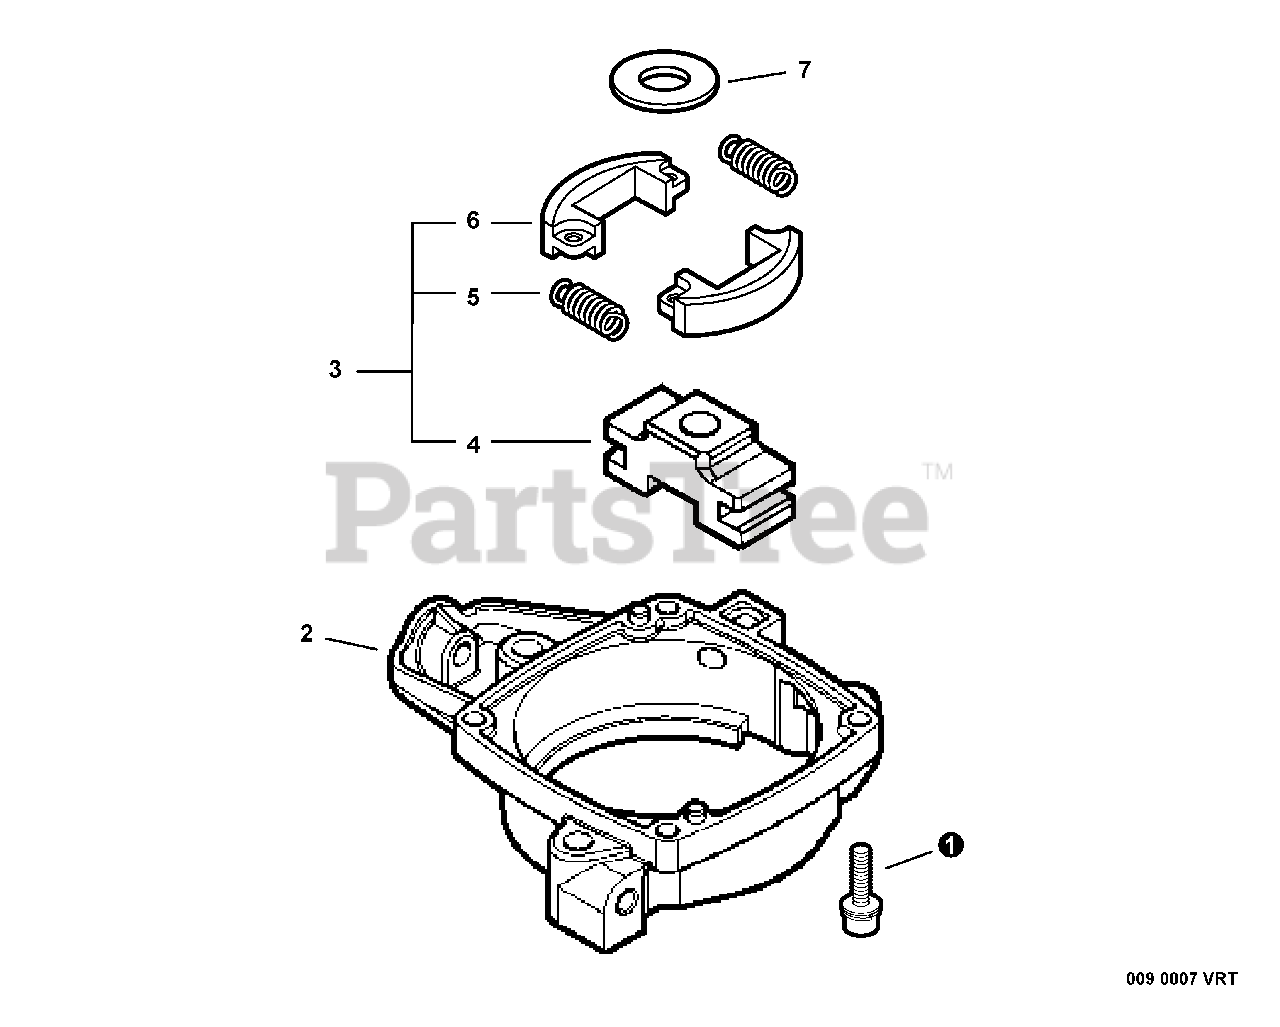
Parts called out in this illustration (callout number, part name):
1	BOLT 4×16
2	CASE, CLUTCH
3	CLUTCH ASSY
4	HUB, CLUTCH
5	SPRING, CLUTCH
6	SHOE, CLUTCH
7	WASHER 8
